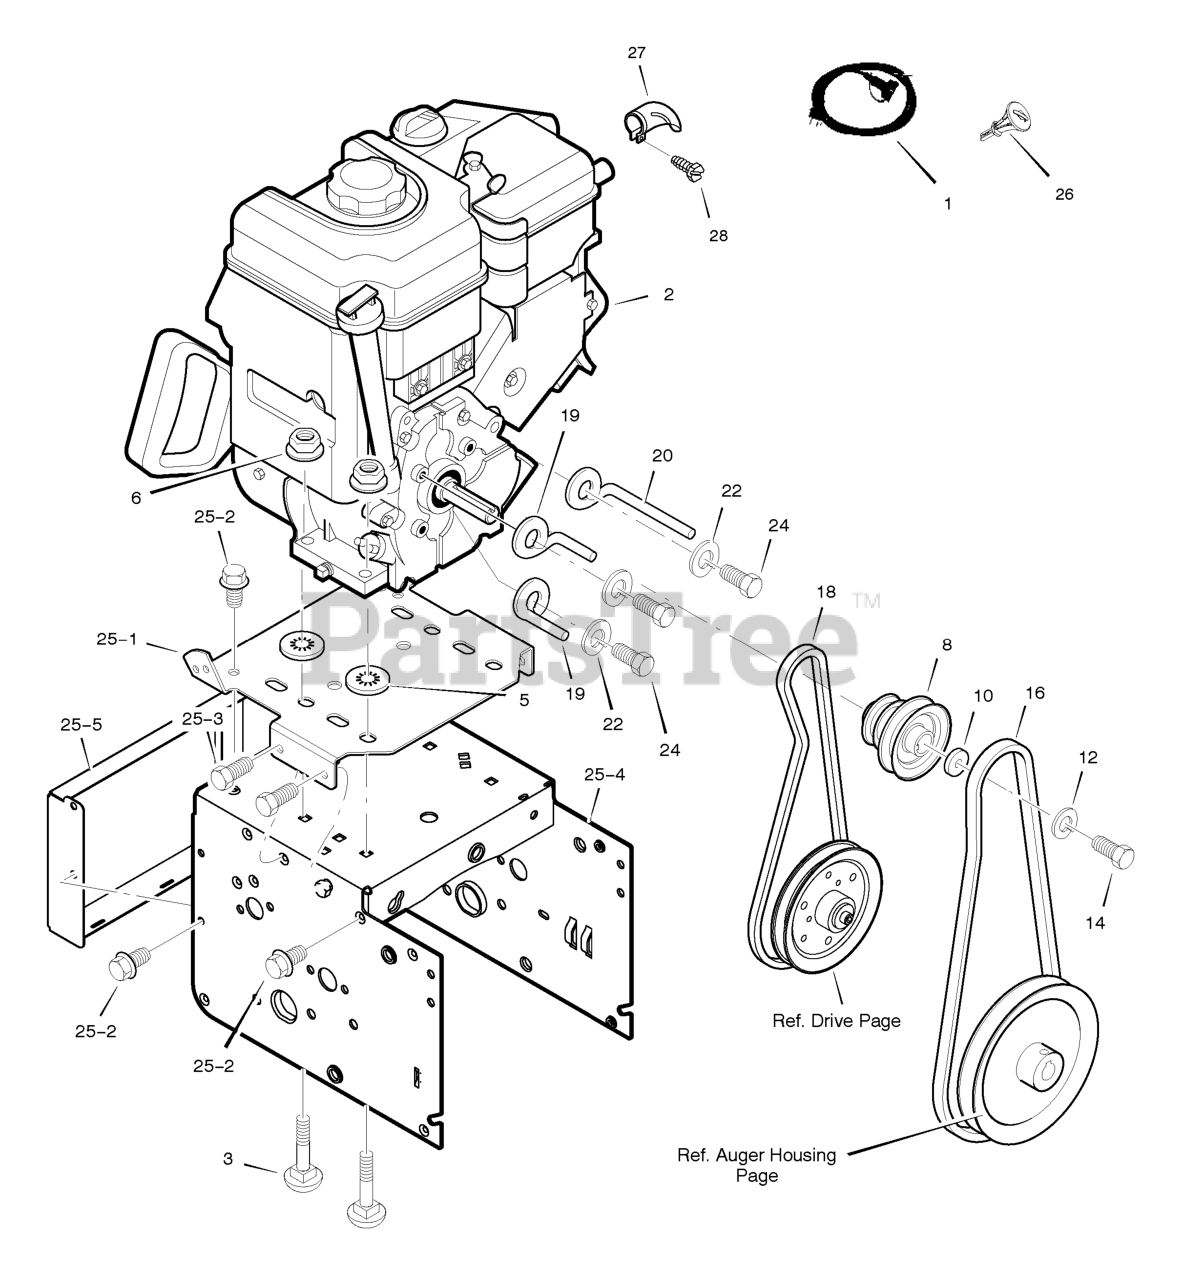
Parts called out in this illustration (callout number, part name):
1	CORD, Electric, 10FT. 110V
2	ENGINE
3	BOLT, CARRIAGE 5/16-18
5	RETAINER, PUSH
6	NUT 5/16-18
8	PULLEY, ENGINE
12	WASHER
14	SCREW, 3/8-24 x 1.00
16	BELT, HYDRO DRIVE
18	BELT, V
19	GUIDE, ROD BELT
20	GUIDE, ROD BELT
22	WASHER, SPTLK .31X.58X.08
24	SCREW, 5/16-24 x 1.00
25	FRAME ASSEMBLY
25-1	PLATE, ENGINE MOUNT
25-2	SCREW 1/4-20 X .63
25-3	SCREW 5/16-18 X .50
25-4	FRAME, MOTOR BOX
25-5	PANEL, BACK
26	KEY, BRIGGS ENGINE
27	DEFLECTOR, Muffler
